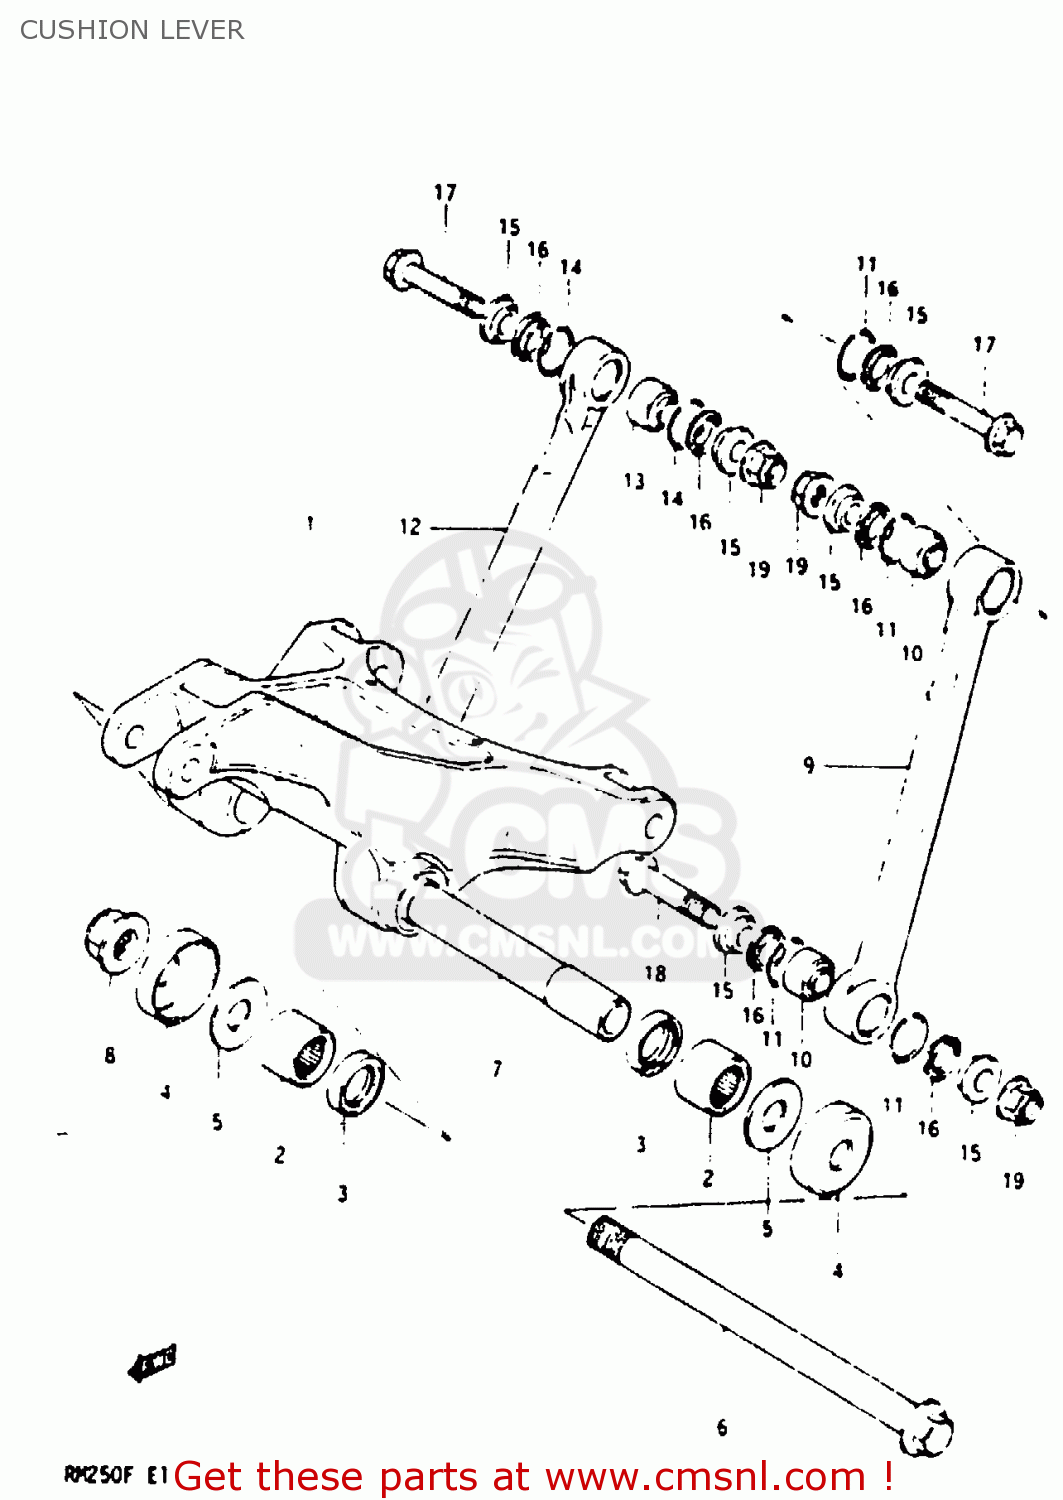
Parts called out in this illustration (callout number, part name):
1	LEVER SET,REAR CUSHION
2	BEARING(20X27X25)
3	SEAL,CUSHION LEVER DUST
4	CVR,RR SWGARM DUST SEAL(OD:40)
5	WASHER
6	SHAFT,REAR CUSHION LEVER
7	SPACER,REAR CUSHION LEVER
8	NUT
9	LEVER SET,REAR CUSHION
10	BEARING(10X21X13)
11	RING,BEARING STOPPER
12	LEVER SET,REAR CUSHION
13	BEARING(10X21X13)
14	RING,BEARING STOPPER
15	SPACER,REAR CUSHION ROD
16	DUST SEAL,RR CUSHION ROD
17	BOLT,RR CUSHION ROD UPR
18	BOLT,RR CUSHION ROD LWR
19	NUT
